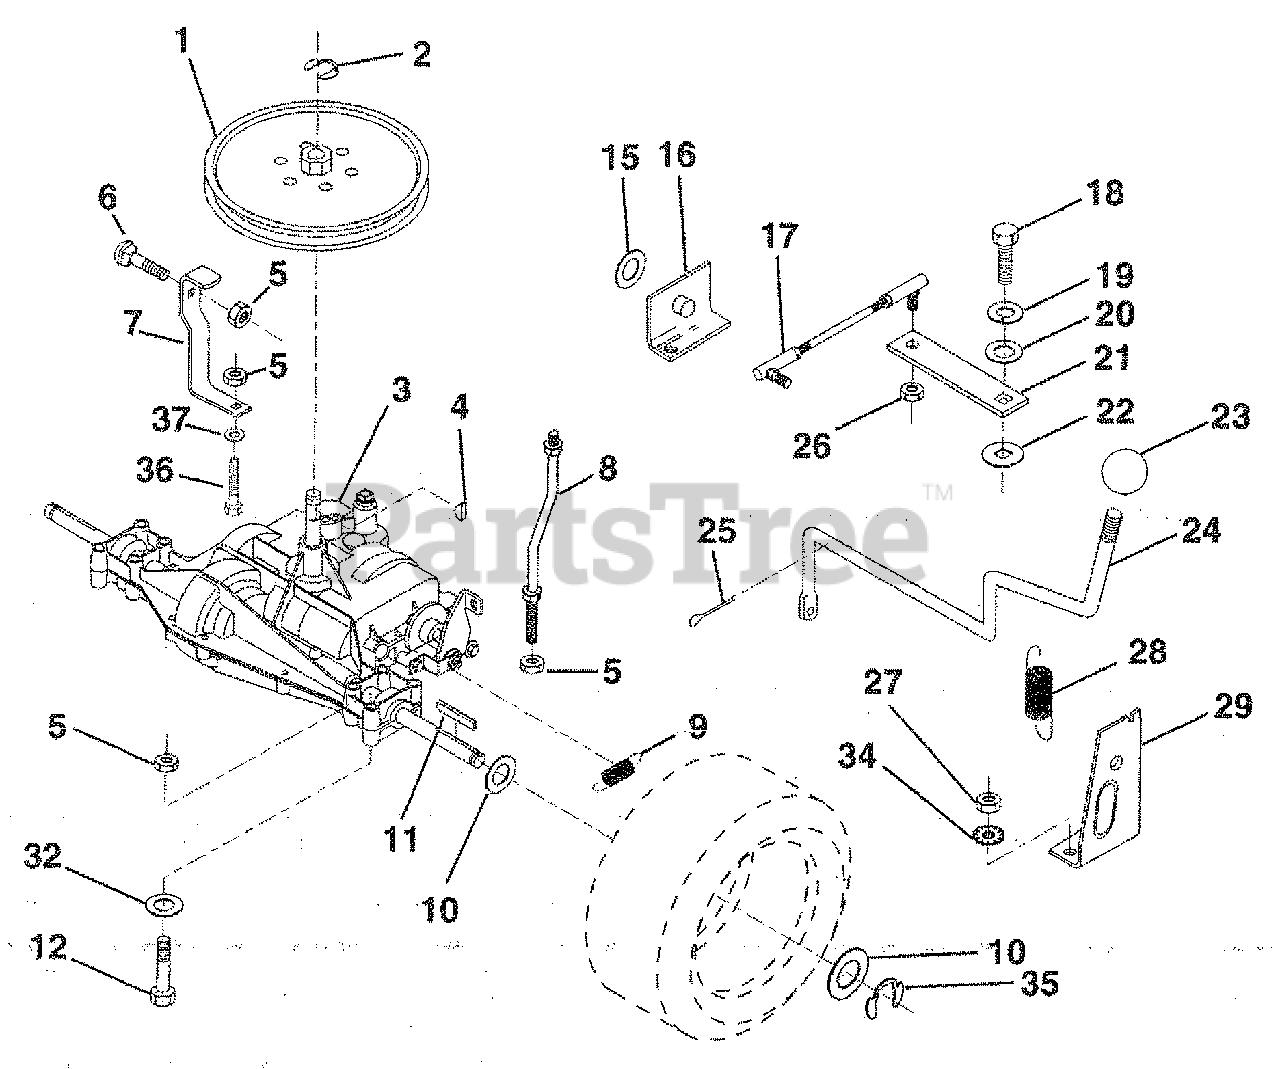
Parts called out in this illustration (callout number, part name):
2	Ring, Retainer
3	Transaxle, 4 Speed, Peerless Model #940-010
4	Key, Woodruff #9
5	Nut, Crownlock 5/16-18
6	Bolt, Carriage 5/16-18 UNC x 3/4
7	Strap, Torque
8	Keeper Belt
9	Spring, Brake
10	Washer 25/32 x 1-1/4 x 16 Ga.
11	Key, Square
12	Bolt Fin Hex 5/16-18 UNC x 2-1/4
15	Washer 17/32 x 1 x 16 Ga
16	Support Handle Shift LH
17	Link, Shift
18	Bolt, Fin Hex 1/4-28 UNF x 3/4 Gr. 8
19	Washer, Lock 1/4
20	Washer 9/32 x 3/4 x 10 Ga.
21	Arm, Shift
22	Washer, Shift Plate
24	Handle, Shift Rod
25	Pin, Cotter 1/8 x 1
26	Nut, Hex Nylon
27	Nut, Keps 5/16 - 18
28	Extension, Spring
29	Support Handle Shift RH
32	Washer
34	Washer, Ext., Tooth, Lock 5/16
36	Bolt, Fin Hex 5/16-18 UNC x 2" Gr 2
37	Washer 11/32 x 5/8 x 16 Ga
